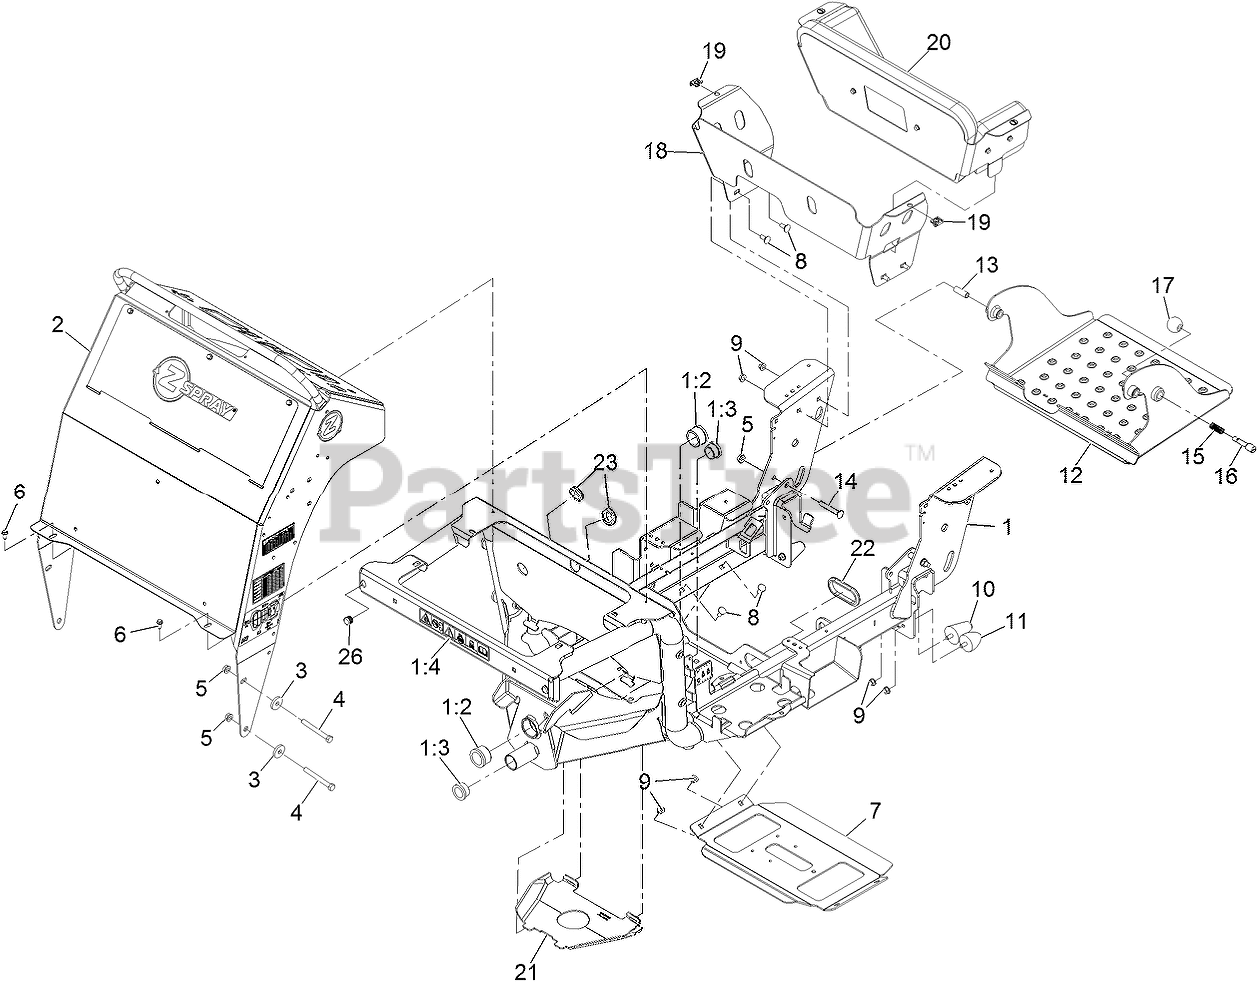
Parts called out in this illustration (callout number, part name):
1	Frame ASM
1:2	BEARING-FLANGED
1:3	BEARING-FLANGED
1:4	DECAL-DOWN, TIE
2	Control Tower ASM
4	SCREW-HH
6	SCREW-HWH
7	GUARD-LOWER
8	SCREW-CARR
10	BUMPER-RUBBER
11	BUMPER-RUBBER
12	OPERATOR PLATFORM ASM
13	BUSHING-PIVOT, PLATFORM
14	SCREW-CARR
16	PIN-LATCH
17	KNOB-BALL
18	MOUNT-PAD, KNEE
19	RECEPTACLE-CLIP, MINI
20	ASM-Pad
21	SHIELD-DUST
22	GROMMET
23	GROMMET
26	PLUG-TUBE
